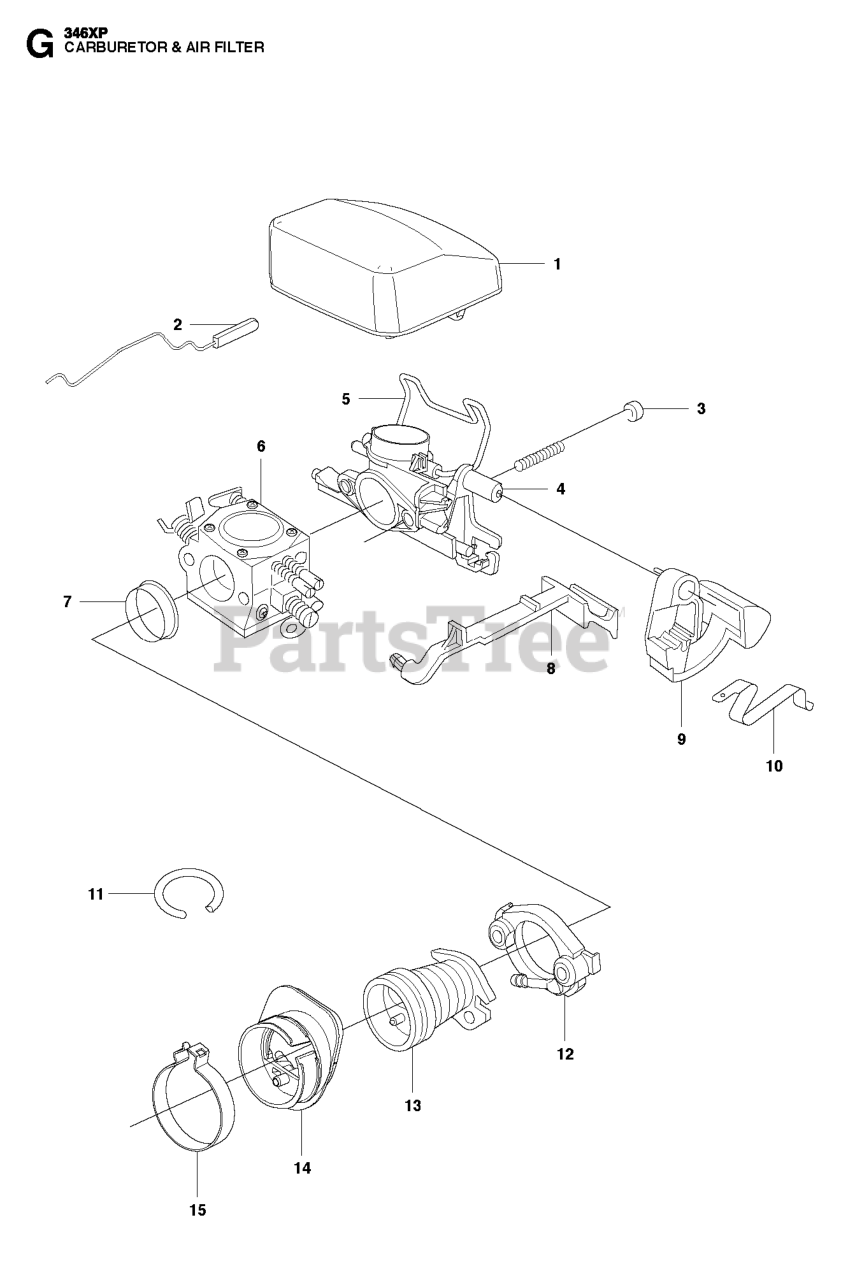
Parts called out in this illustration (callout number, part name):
1	AIR FILTER - NYLON (B)
1	AIR FILTER - NYLON (Y)
1	AIR FILTER - FELT
2	THROTTLE ROD
4	INLET ELBOW
5	FILTER CLAMP
6	CARBURETOR
8	CHOKE CONTROL
11	HOSE, IMPULSE
12	FLANGE
15	CLAMP, INTAKE
